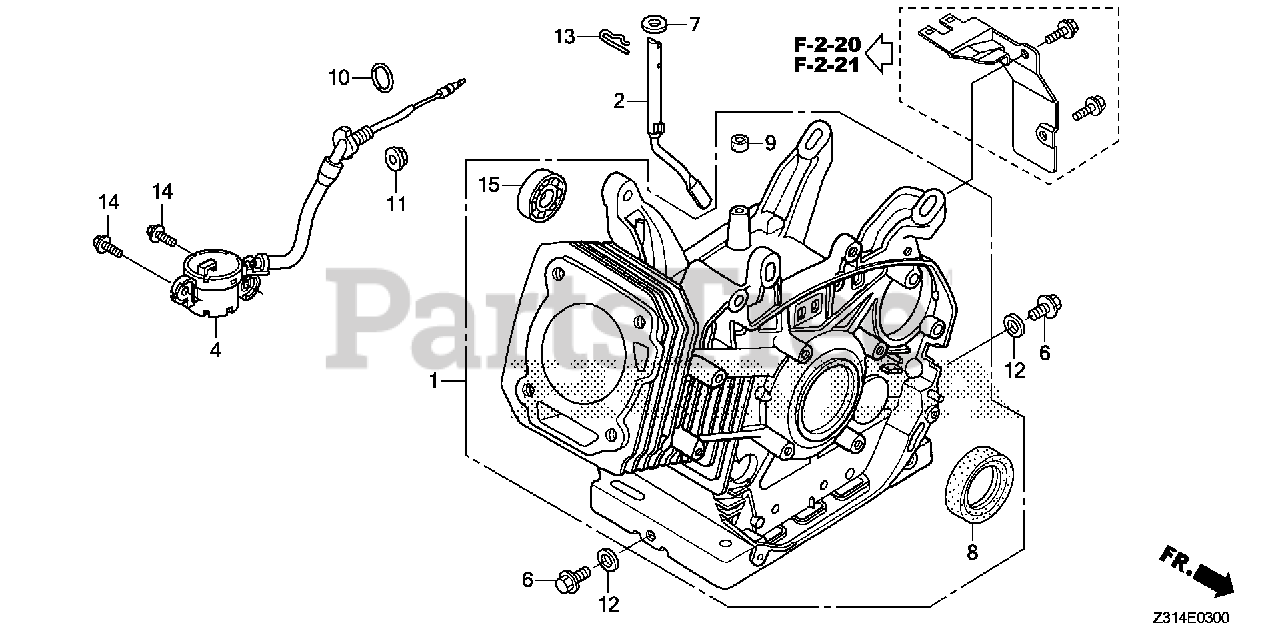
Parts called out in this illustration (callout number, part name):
1	CYLINDER ASSY. (ALERT)
2	SHAFT, GOVERNOR ARM
4	SWITCH ASSY., OIL LEVEL
6	BOLT, DRAIN PLUG (12X15)
7	WASHER (8.2X17X0.8)
8	OIL SEAL (35X52X8) (NOK)
9	OIL SEAL (8X14X5)
10	O-RING (13.5X1.5) (ARAI)
10	O-RING (14MM) (NOK)
11	NUT, FLANGE (10MM)
12	WASHER, DRAIN PLUG (12MM)
13	PIN, LOCK (10MM)
14	BOLT, FLANGE (6X12)
15	BEARING, RADIAL BALL (6202)
